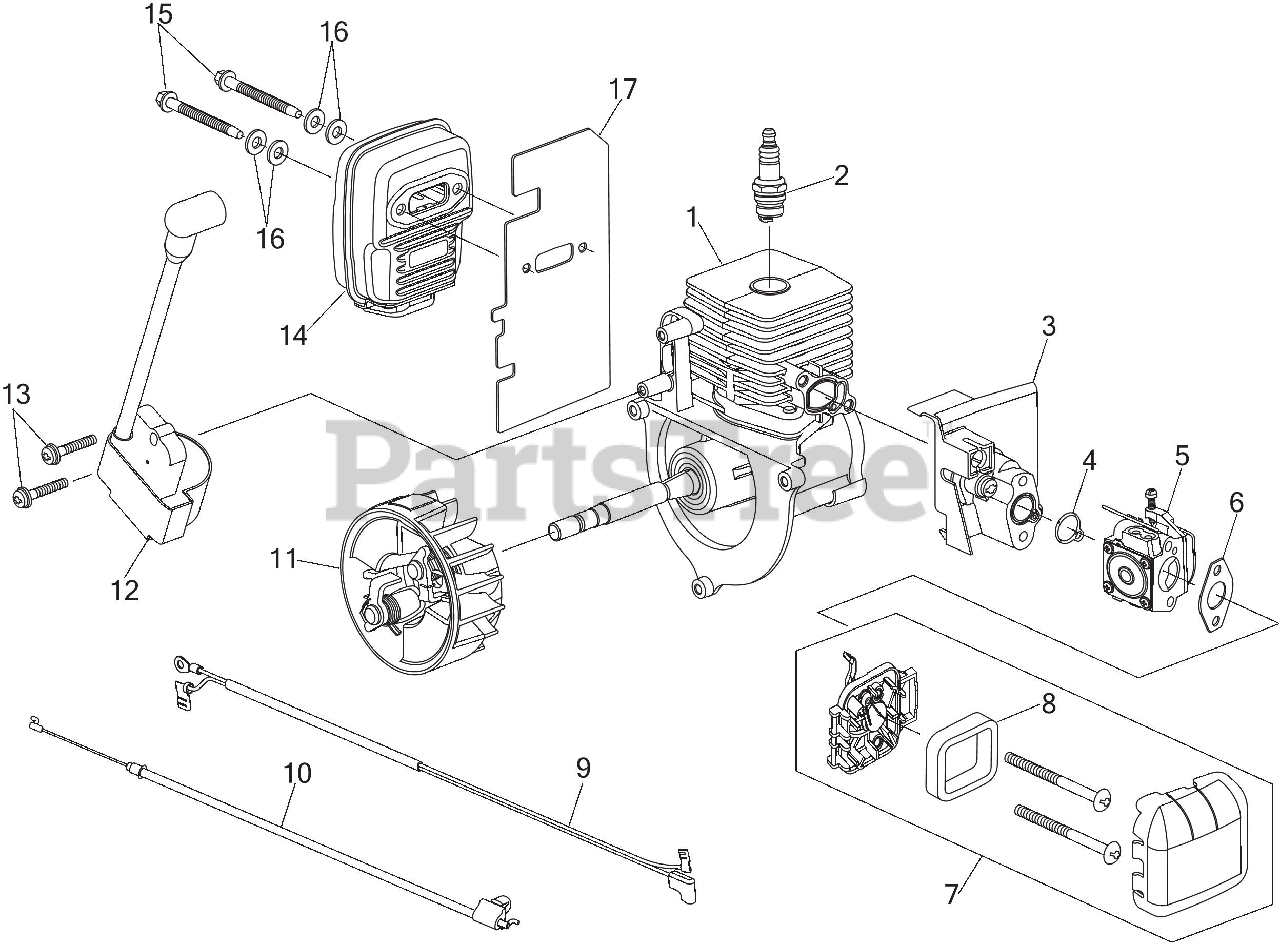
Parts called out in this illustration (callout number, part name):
1	SHORTBLOCK
2	SPARK PLU 14MM
3	INTAKE ASSEMBLY
4	O-RING
5	CARB ASSEMBLY
6	GASKET CARB
7	AIR CLEANER ASSEMBLY
8	AIR FILTER
9	WIRE LEAD
10	THROTTLE CABLE
11	FLYWHEEL ASSEMBLY
12	MODULE ASM W/SLV RFI
13	SCREW 8-32X.750
14	MUFFLER ASSEMBLY
15	MUFFLER SCREW
17	GASKET
